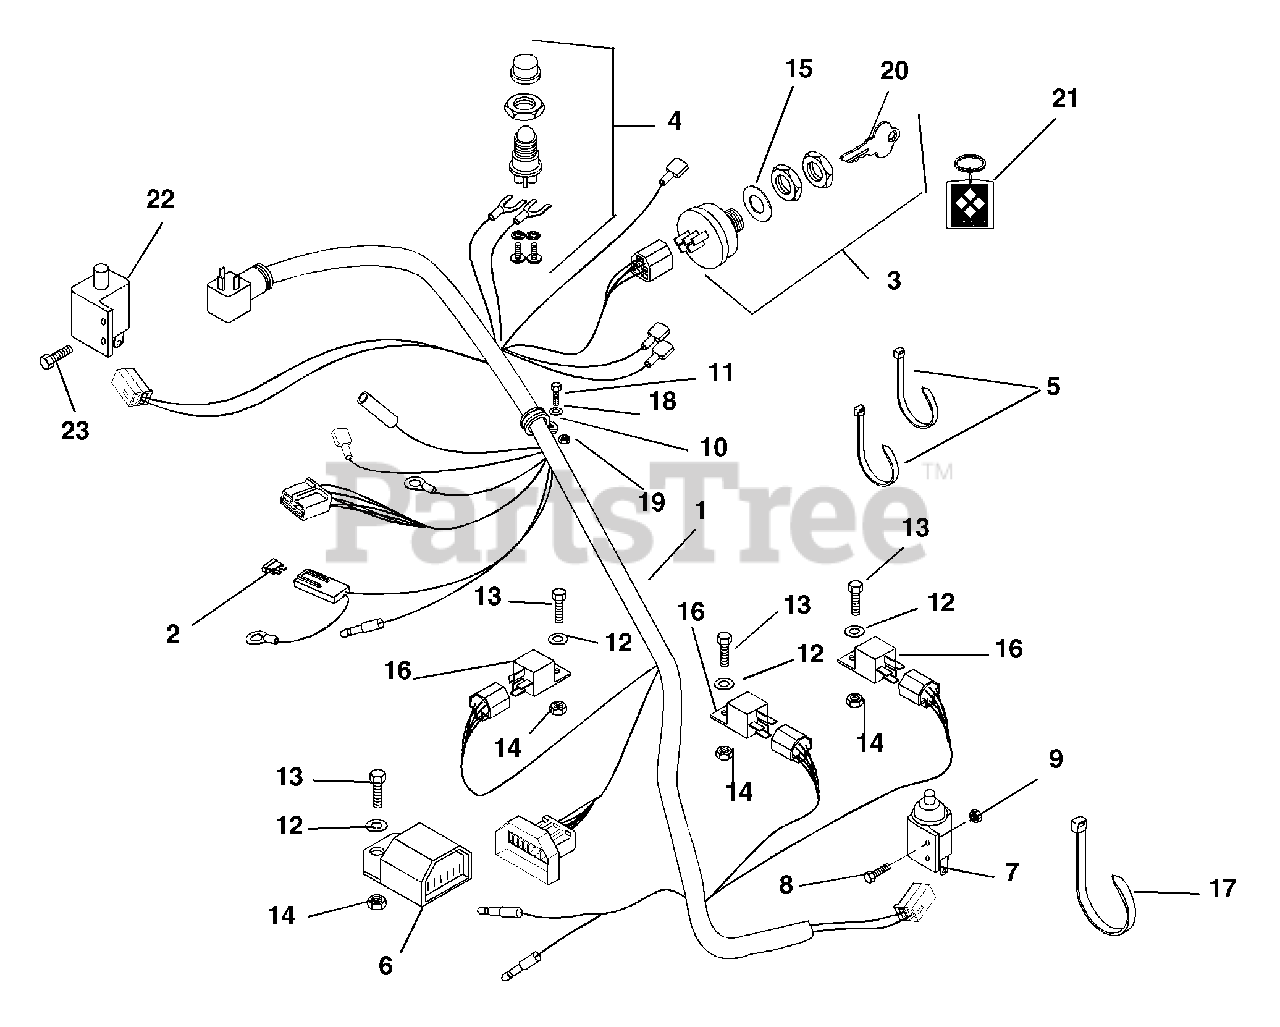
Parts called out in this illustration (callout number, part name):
1	Harness-Wiring 20 H.P. Honda 20 AMP
2	Fuse-25 Amp
3	Switch-Ignition
4	Switch
5	Tie- Wrap 15.25"
6	Module-Interlock Delay
7	Switch-Operator Presence
8	Bolt-Hex M5-.8 x 16
9	Nut-Locking-Nylon M5-.8
10	Clamp-Cushioned Steel
11	Bolt-Hex M6 x 1.0 x 25
12	Washer-Flat-Steel .194 x .492 x .047
13	Bolt-Hex M5 x .80 x 16
14	Nut-Locking-Nylon M5 x .80
15	Washer-Flat-Steel .812 x 1.50 x .135
16	Relay
17	Cable-Tie Large 5-1/2
18	Washer-Flat-Steel .281 x .62 x .065
19	Nut-Locking Nylon M6-1
20	Ignition Key Set
21	Key Chain
22	Switch, Interlock NC
23	Bolt-Hex M5-.8 x 16
